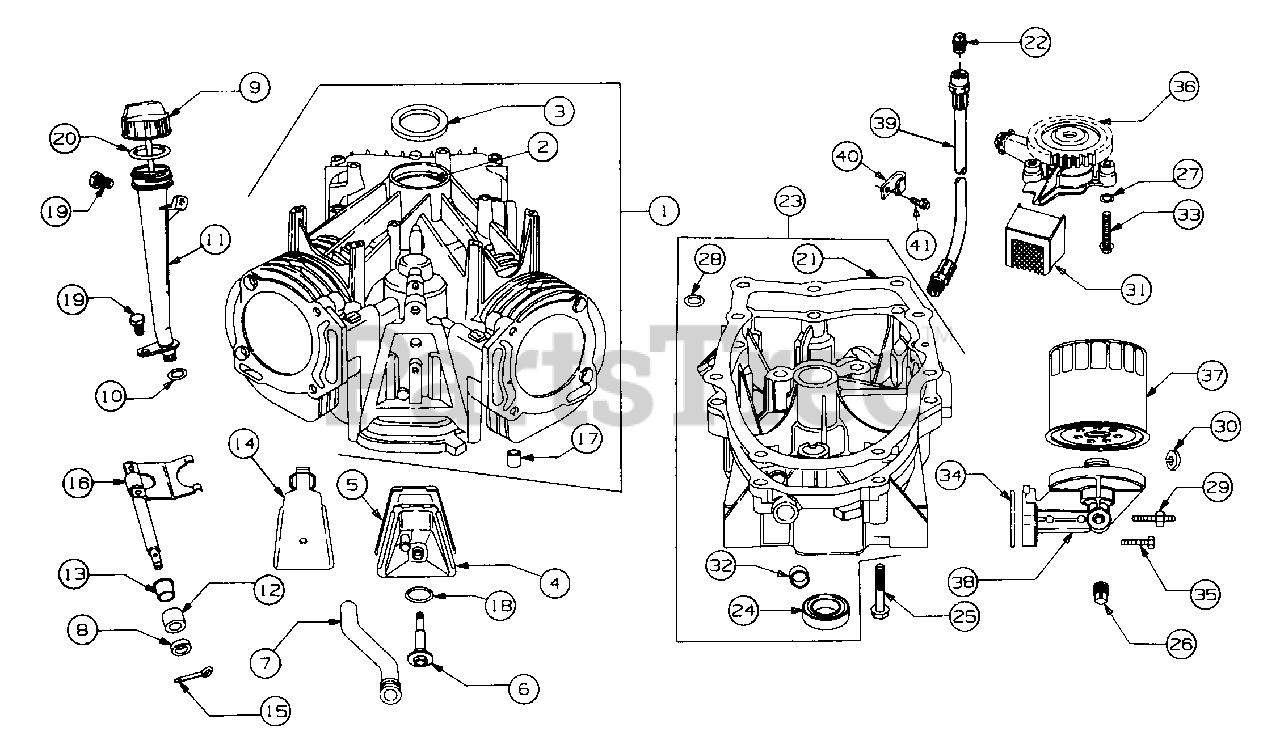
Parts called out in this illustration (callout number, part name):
1	Cylinder Assy
2	Bearing, Cylinder
3	Seal, Oil
4	Breather Assy
5	Gasket, Breather
6	Screw, Breather
7	Tube, Breather
8	Seal, Governor Shaft
9	Dipstick
10	Seal, Filler Tube
11	Tube, Oil Filler
12	Bushing, Governor Shaft
13	Bushing, Governor Shaft
14	Baffle, Breather
15	Pin, Cotter
16	Fork, Governor
17	Dowel, Crankcase
18	Seal, Breather Screw
19	Screw, Mounting
20	O-Ring
21	Gasket, Crankcase Cover
22	Plug, Oil Drain
23	Cover Assy, Crankcase
24	Seal, Oil
25	Screw, Crankcase Cover
26	Plug, Pipe
27	O-Ring (Oil pump)
29	Stud, Oil Filter Adapter
30	Washer, Lock
31	Screen, Oil
32	Washer, Governor Shaft
33	Screw, Sem
34	Gasket, Filter Adapter
35	Screw, Sem
36	Oil Pump Assy
37	Filter, Oil
38	Adapter, Oil Filter
39	Hose, Oil Drain
40	Clip, Drain Hose
41	Screw, Hex Wash Hd Tapp, 5/16-18 X .50 Lg
